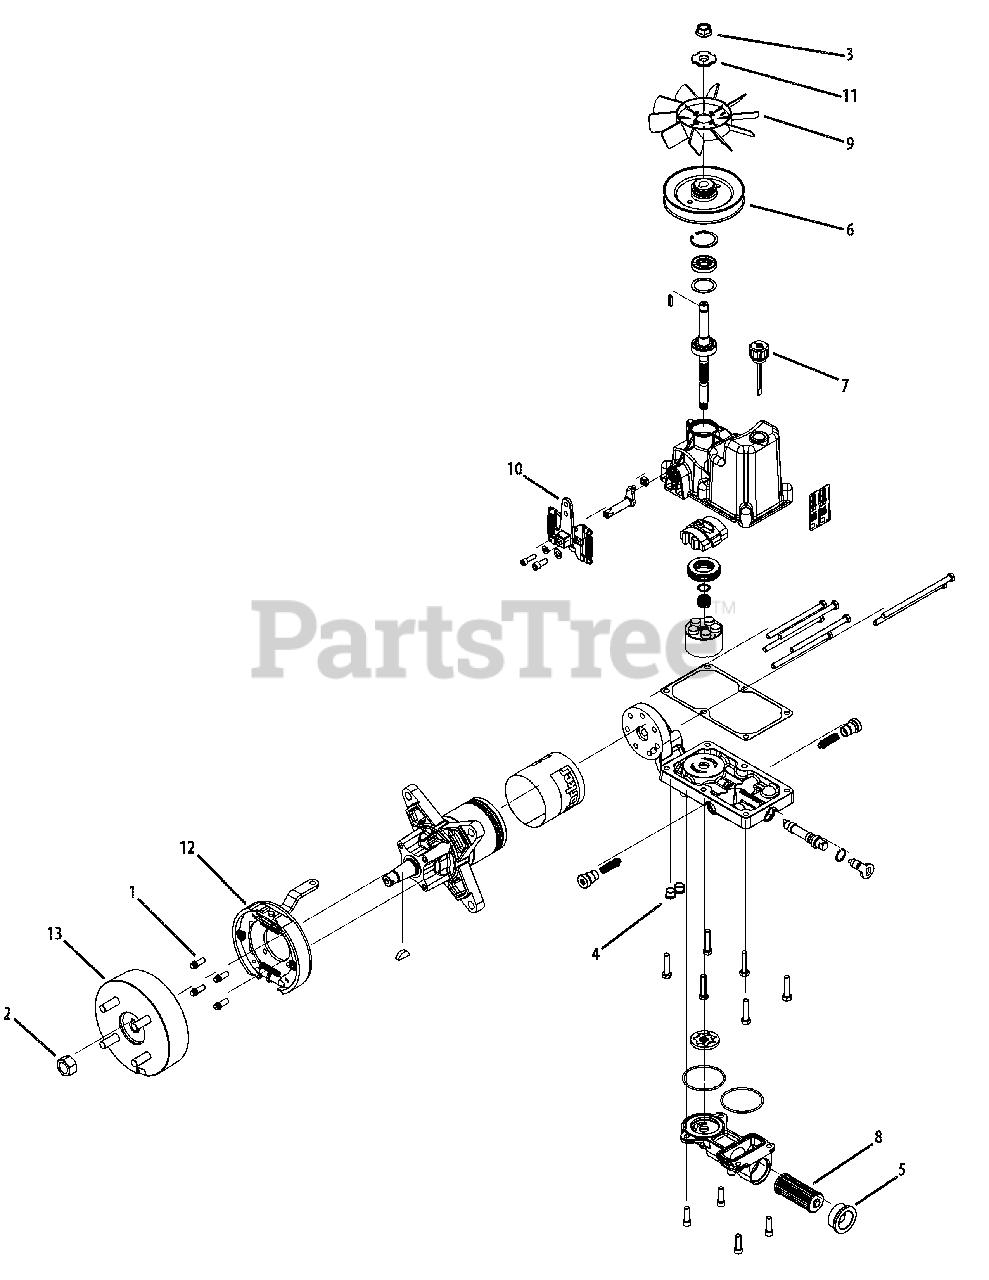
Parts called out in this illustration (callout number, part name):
1	Flange Head Screw
3	Nut, Flange 1/2-20 UNF
4	Plug, Magnetic Hex
5	Plug & O-Ring Assembly
6	Pulley (5")
7	Breather
10	SA, RTN
11	Fan Spacer
12	Brake Assembly
13	Drum Assembly, 4 Bolt, 1" Shaft
